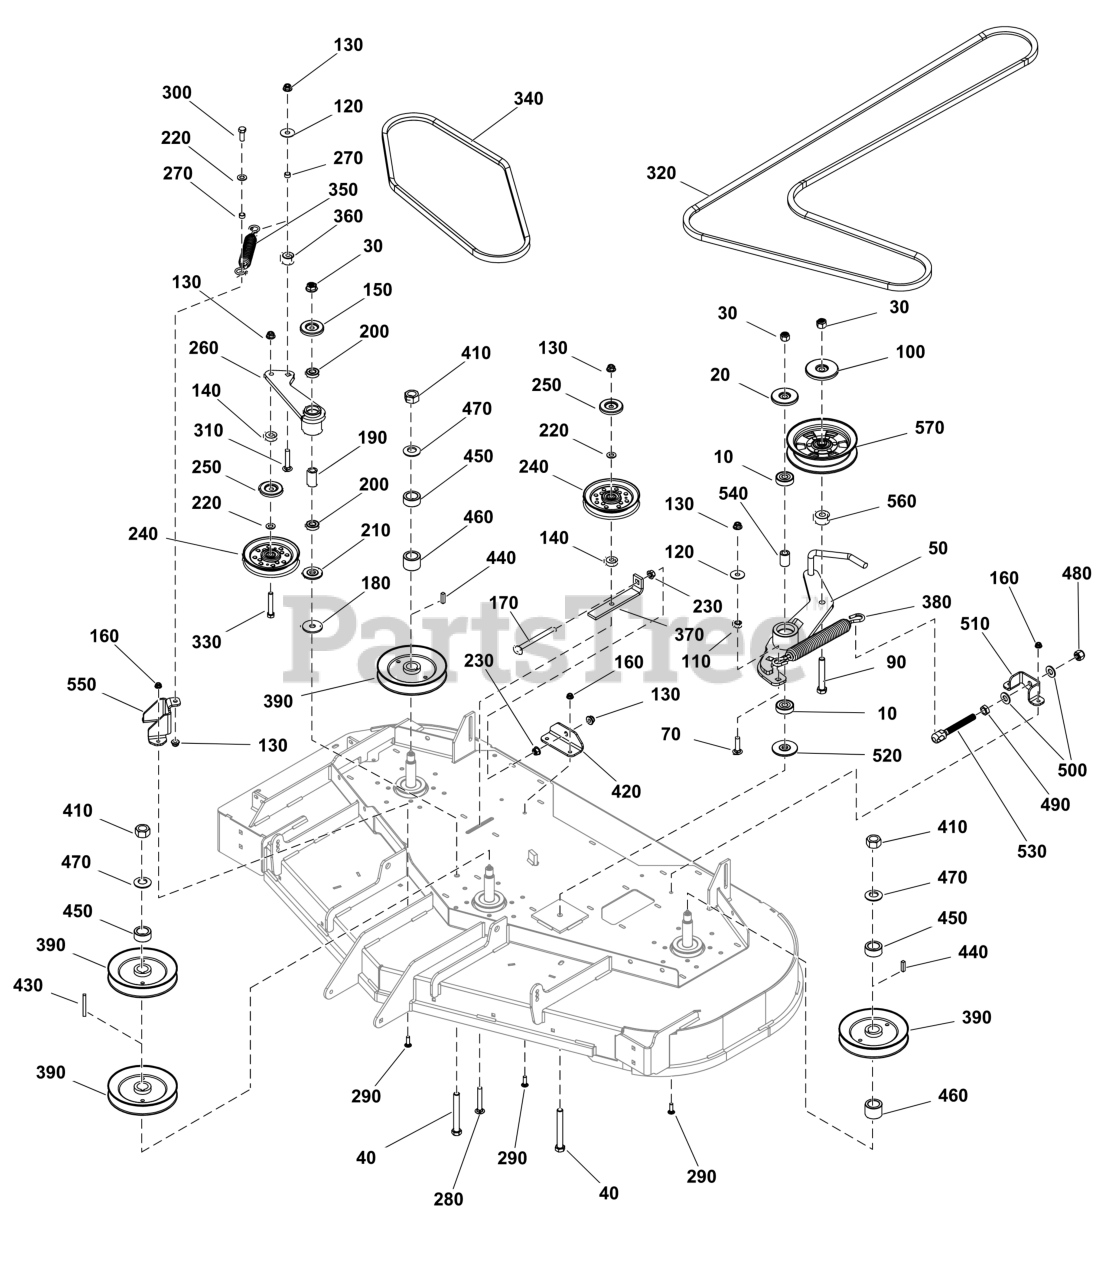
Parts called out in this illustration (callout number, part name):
20	SHIELD, BEARING, 1/2" ID-2.5"
40	BOLT, 1/2-13 X 4 GD5
50	ARM-IDLER
90	BOLT, 1/2-13 X 2-3/4"
120	WASHER, 3/8" FENDER
130	NUT, 3/8-16 HEX NYLOCK
150	SHIELD, BEARING, 1/2" ID-1.75"
160	NUT
190	SPACER, .52 X .84 X 1
200	BEARING, BALL, AXLE
210	SPACER, IDLER ARM
230	NUT, 3/8-16 HEX SERRA
260	WELD, IDLER ARM, RH BELT - BLK
270	SPACER, .38 X .50 X .
280	BOLT, Carriage, 3/8-16 x 2-1/2
290	BOLT, 5/16-18 X 1", C
300	BOLT, 3/8-16 X 1" GD5
310	BOLT, 3/8-16 X 2", CA
330	BOLT, 3/8-16 X 2-1/4"
350	SPRING, EXTENSION, SW
410	NUT, 3/4-16 HEX
420	PLATE, PULLER MOUNT, SPRING-BLK
430	KEY - 1/4 SQX2 1/4
440	KEY, 1/4" SQ. X 1.00
470	WASHER, Beveled
480	NUT, 1/2-20 HEX NYLON
490	NUT, 1/2-20 HEX JAM
500	WASHER, 1/2" SAE
510	PLATE, IDLER BOLT, LONG-BLK
530	ANCHOR, SPRING
540	SPACER, .51 X .84 X 1
550	PLATE, SPRING MOUNT - BLK
560	SPACER, .52 X 1.00 X
570	PULLEY, IDLER
